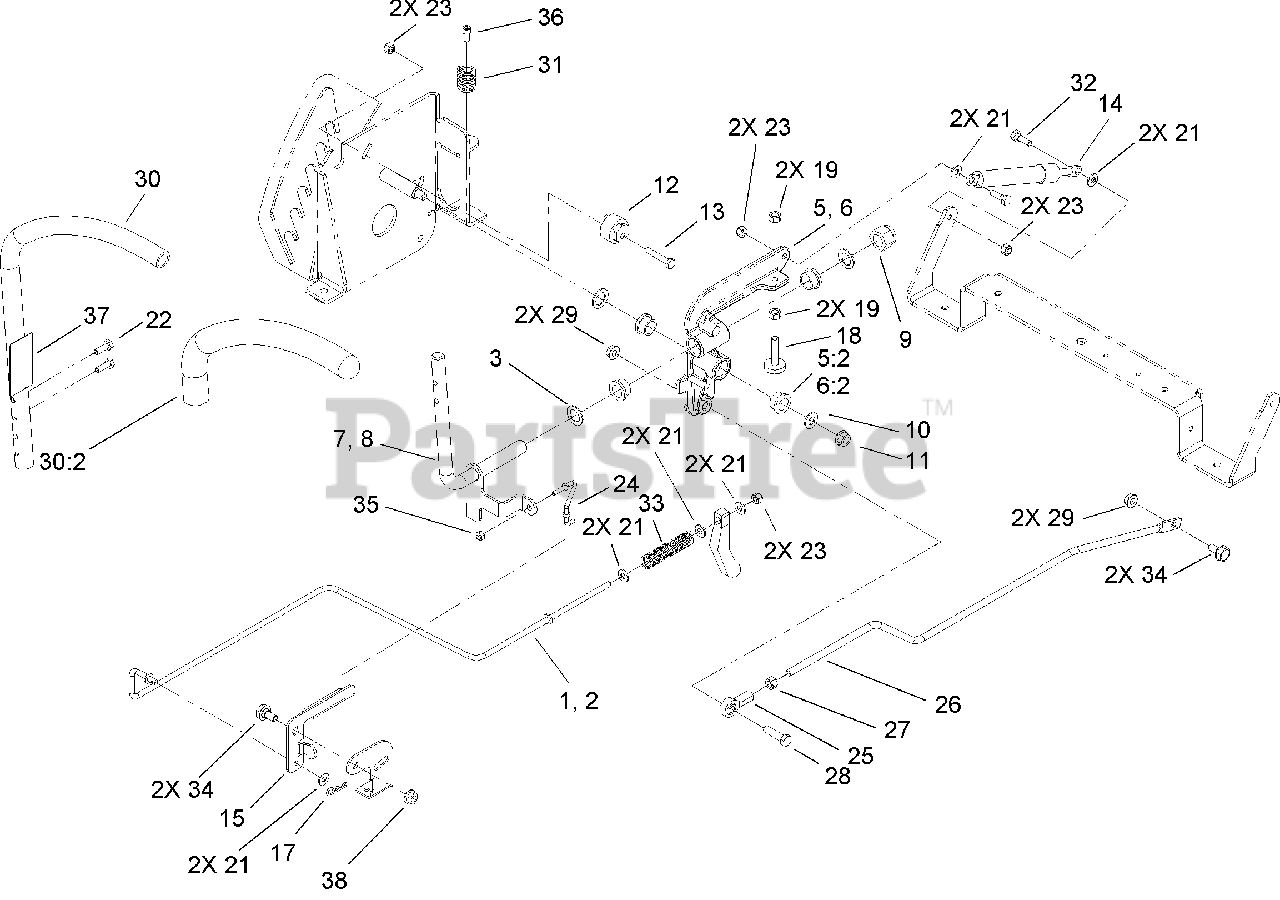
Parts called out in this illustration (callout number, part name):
1	ROD-BRAKE, LH
2	ROD-BRAKE, RH
3	WASHER-THRUST
6	RH ACTIVATOR ARM ASM
8	RH PIVOT SHAFT ASM
9	NUT-LOCK, NI
10	WASHER-FLAT
11	NUT-LOCK, NI
12	ECCENTRIC
13	SCREW-HH
14	Damper-Control, Motion
15	BELLCRANK
18	STOP-ADJUSTMENT
19	NUT-HEX
21	WASHER-FLAT
22	SCREW-HH
23	NUT-LOCK, NI
24	LINK-BRAKE
25	BALLJOINT-RH
26	ROD-HYDRO
27	NUT-HEX
28	SCREW-HH
30	HANDLE ASM
31	SPRING-COMPRESSION
32	BOLT-SHOULDER
33	SPRING-COMPRESSION
34	BOLT-SHOULDER
35	NUT-LOCK
36	SCREW-HSH
